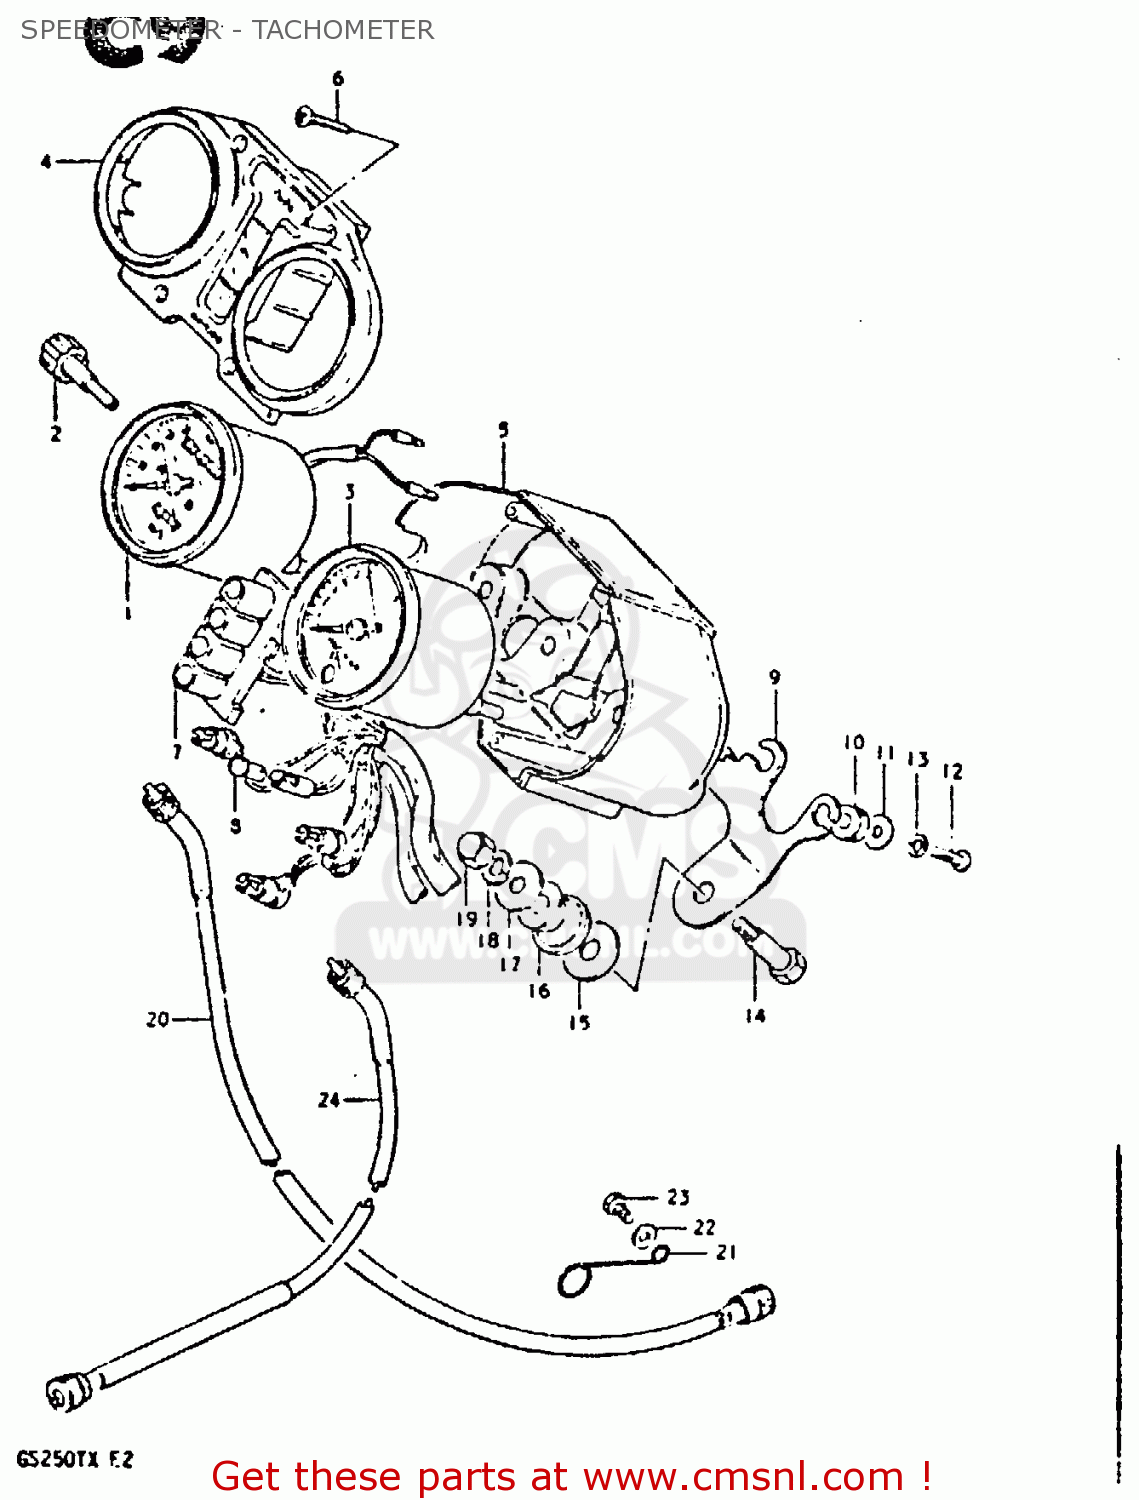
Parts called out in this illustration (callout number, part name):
1	METER,SPEEDOMETER (KM/MPH)
2	KNOB,TRIP METER
3	TACHOMETER
4	HOOD,METER
5	VISOR,LWR
6	SCREW
7	SOCKET,METER
8	BULB(12V3.4W,T10)
9	BRACKET,METER
10	CUSHION
11	WASHER,METER
12	SCREW
13	LOCK WASHER
14	BOLT
15	WASHER
16	CUSHION,METER BRACKET
17	WASHER(8.5X23X1.2)
18	LOCK WASHER
19	NUT
20	CABLE ASSEMBLY,SPEEDOMETER
21	GUIDE,SPEEDOMETER CABLE
22	WASHER
23	BOLT, UPPER
24	CABLE ASSEMBLY,TACHOMETER
